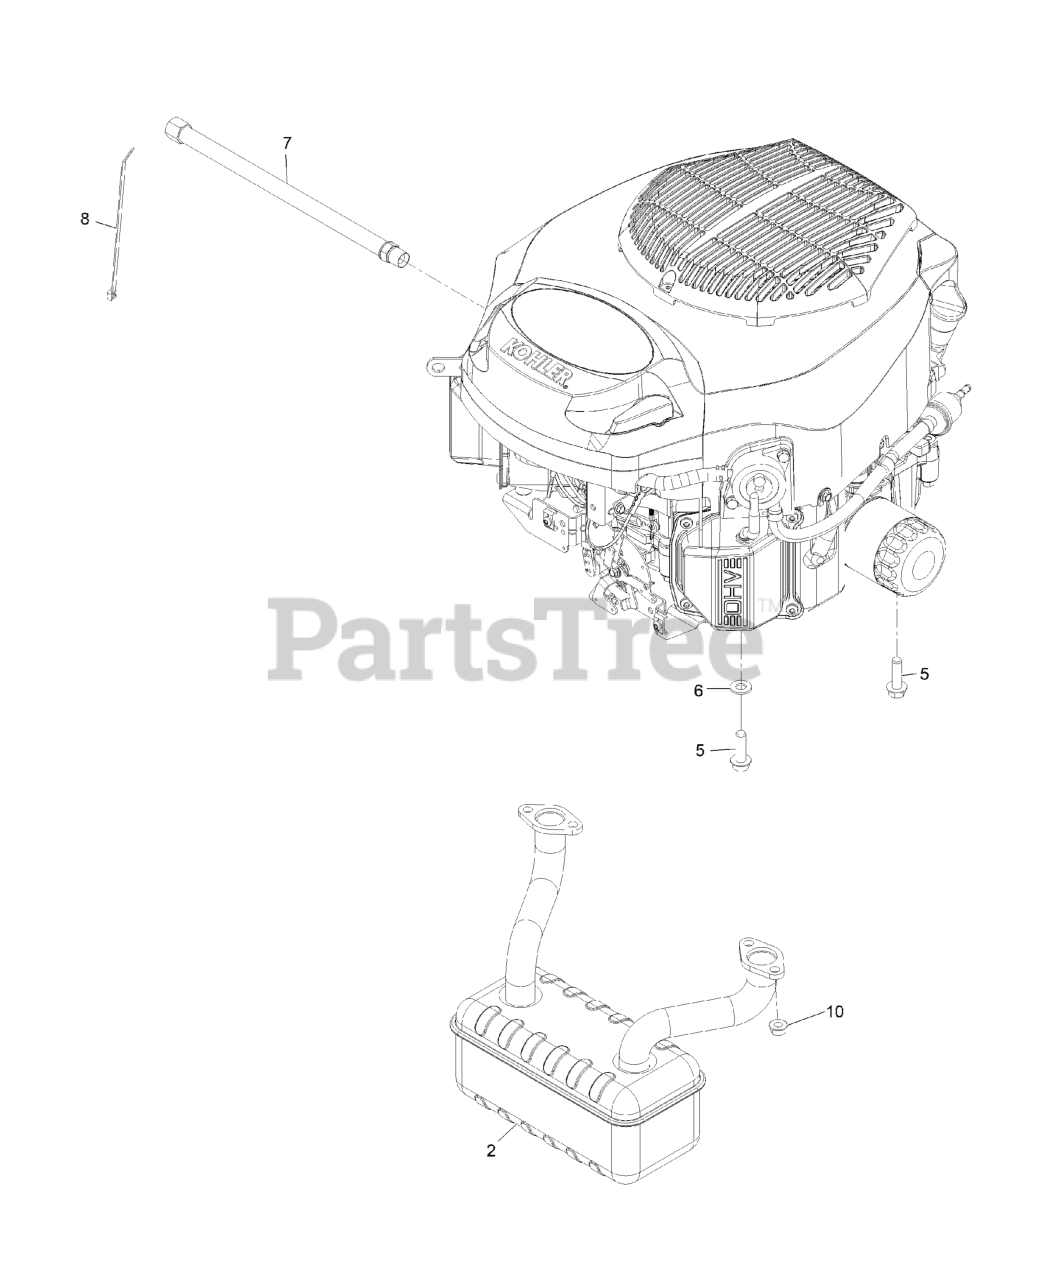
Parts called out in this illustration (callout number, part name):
2	MUFFLER
5	SCREW-THD
6	WASHER-FLAT
7	HOSE-DRAIN, OIL
8	TIE-CABLE
